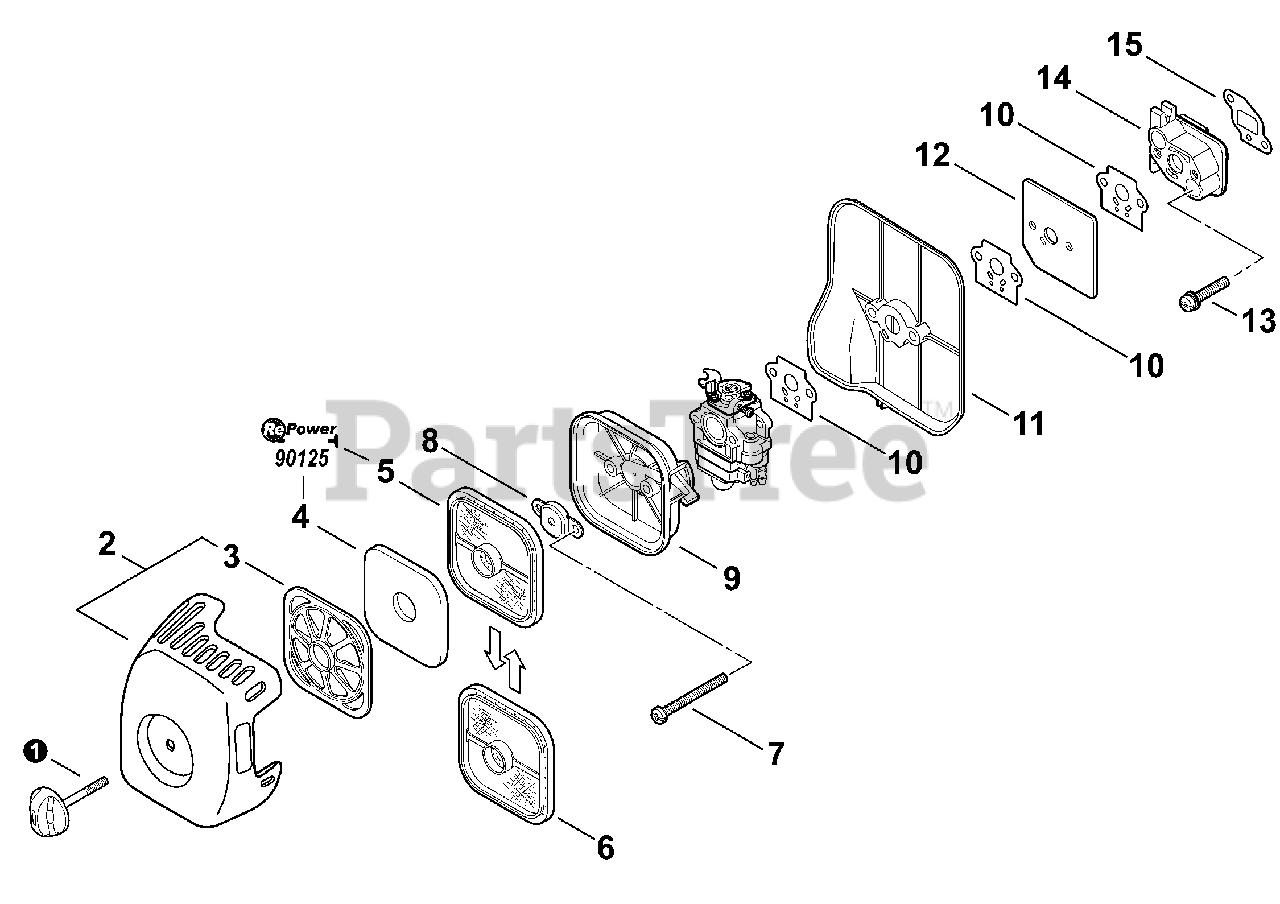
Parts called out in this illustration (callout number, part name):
1	THUMBSCREW
2	COVER KIT, AIR FILTER
3	RETAINER, PRE-FILTER
4	PRE-FILTER, FOAM
5	FILTER, AIR - DOUBLE LAYER
6	FILTER, AIR - SINGLE LAYER
7	SCREW 5×70
8	PLATE, PREVENT
9	CASE, AIR FILTER
10	GASKET, INTAKE
11	PLATE, INSULATOR
12	PLATE, INSULATOR
13	BOLT 5×30
14	INSULATOR, INTAKE
15	GASKET, INTAKE
